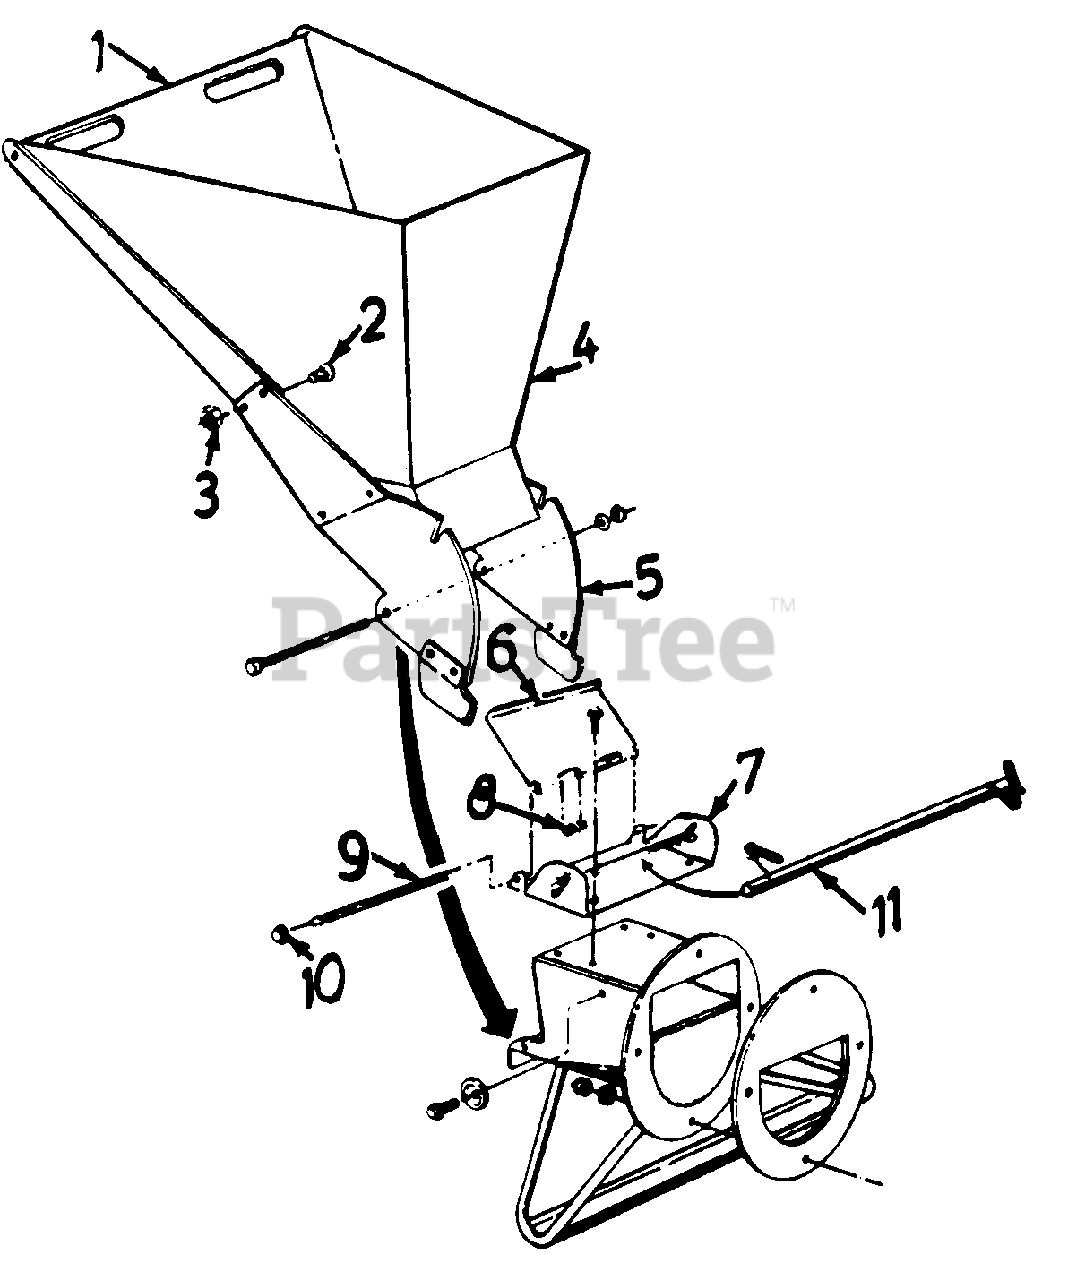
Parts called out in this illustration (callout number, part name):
3	HEX L-NUT 1/4-20 THD.
9	HOPPER DOOR ROD
10	CAP SPEED NUT 1/4 ROD
11	RELEASE BAR
